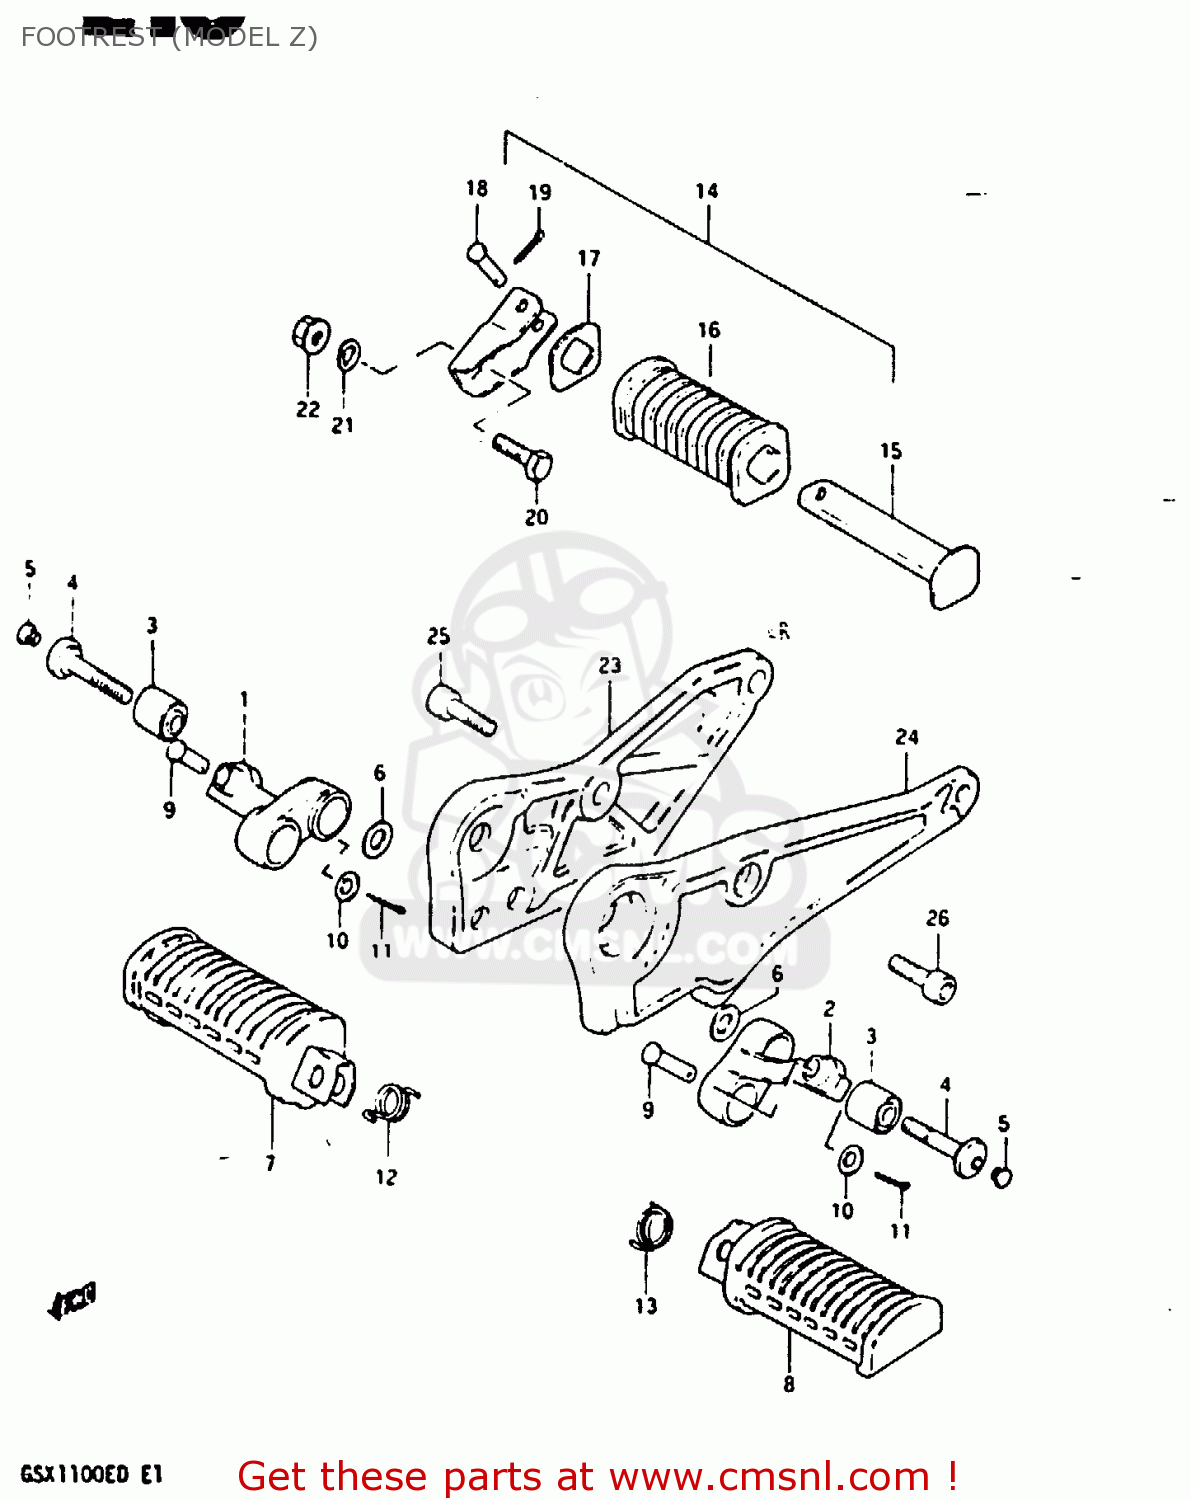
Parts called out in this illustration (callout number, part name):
1	BAR,FRONT FOOTREST,RIGHT
2	BAR,FRONT FOOTREST,LEFT
3	BUSH
4	BOLT(10X50)
5	CAP
6	WASHER
7	RUBBER,FOOTREST
8	FOOTREST
9	PIN
10	WASHER
11	PIN 20X20
12	SPRING
13	SPRING
14	FOOTREST ASSEMBLY,REAR
15	BAR,REAR FOOTREST
16	RUBBER,REAR FOOTREST
17	WASHER,REAR FOOTREST RUBBER
18	PIN
19	PIN 20X20
20	BOLT,M10X1.25X
21	LOCK WASHER
22	NUT
23	BRACKET,MUFFLER,RIGHT
24	BRACKET
25	BOLT
26	BOLT
